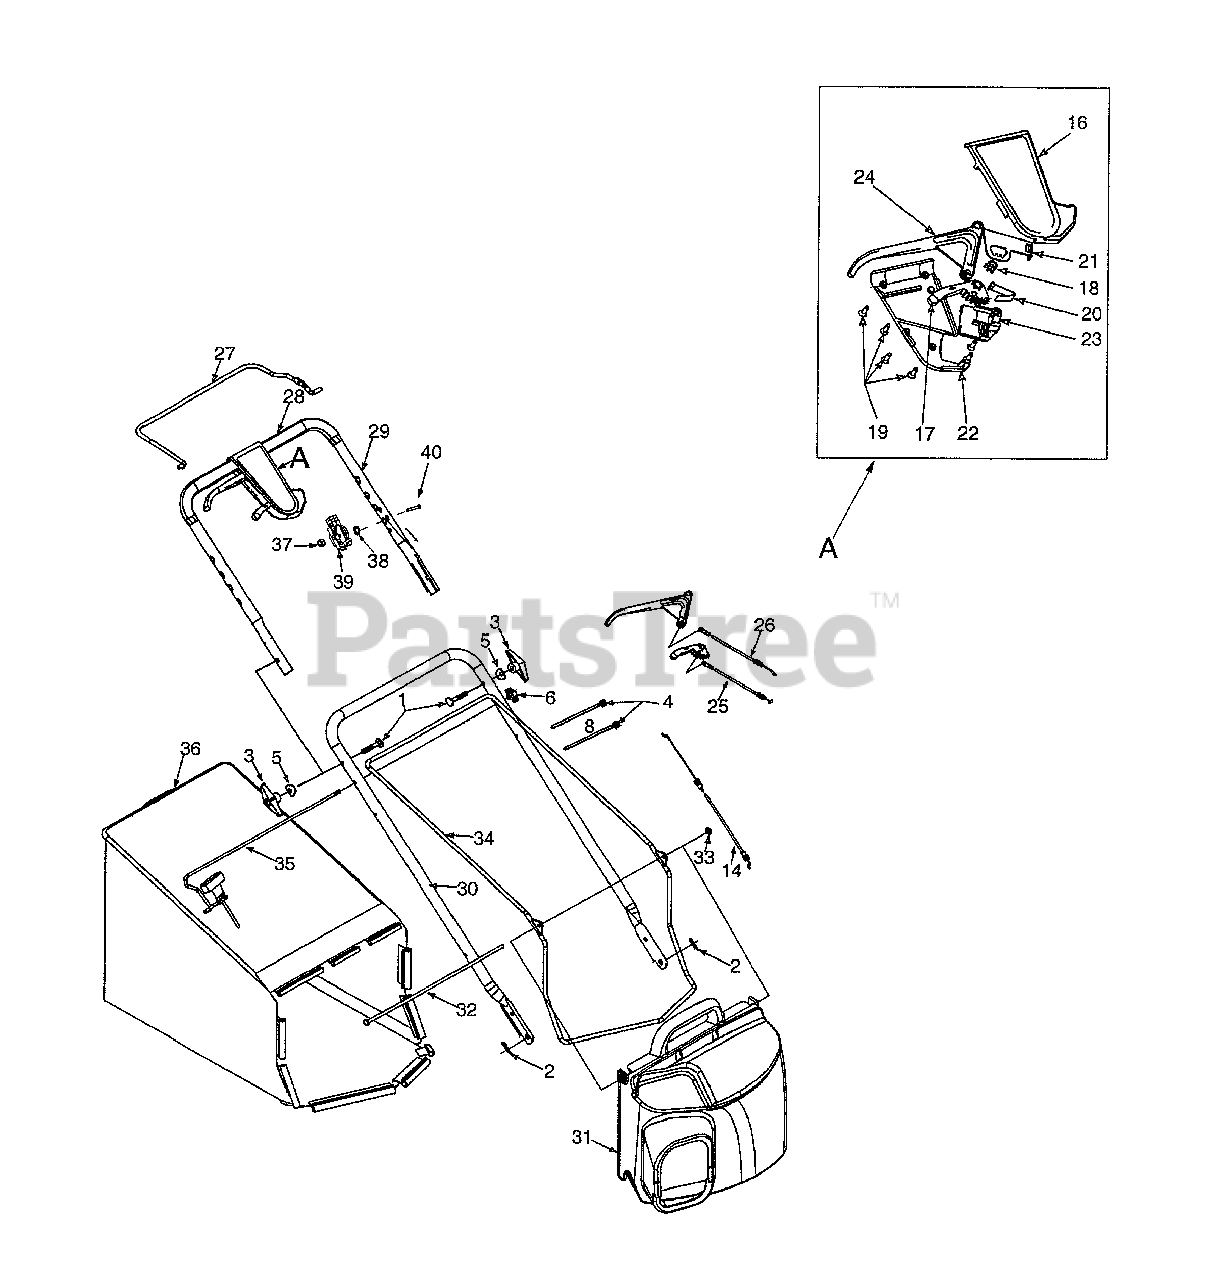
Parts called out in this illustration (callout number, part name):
1	Bolt Cur. Carr. 5/16-18 x 2.0
2	Cotter Pin .072 x 1.12 Lg.
3	Wingknob 5/16-18
4	Strap 4.3 Lg.
5	Wash. Sad. .320 1 D x .830 OD
6	Handle Knob, 1/4-20
8	Screw 1/4-20 x 1.3
14	Control Cable 44" Lg.
16	Upper Control Housing
17	6 Speed Shift Lever
18	Gear Insert
19	C Sunk Tap Screw #10-16x.625
20	Shift Lever Spring
21	6 Spd. Rack Cable Brkt.
22	Lower Control Housing
23	Cable Mounting Cap
24	Control Lever
25	6 Spd. Cable
26	Self Prop. Cable 52"
28	Foam Grip
31	Grassbag Cover w/Logo
32	Pivot Rod
33	Cap Nut
36	Grassbag
37	Hex Lock Nut, 1/4-20
38	Curved Wash .663 x .980 x .014
39	Throttle/Choke Housing
40	Oval C-Sunk Screw 1/4-20 x 1.825
